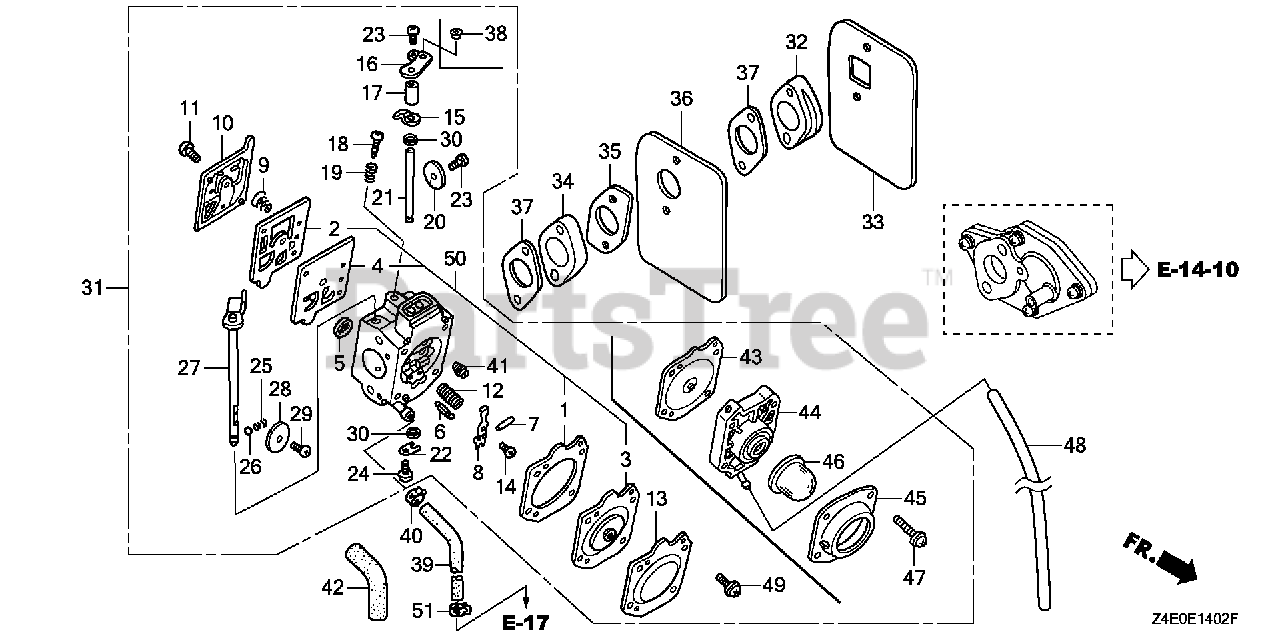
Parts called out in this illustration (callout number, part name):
1	GASKET, METERING DIAPHRAGM (CARBURETOR NO.)
2	GASKET, PUMP
3	DIAPHRAGM ASSY., METERING (CARBURETOR NO.)
4	DIAPHRAGM, PUMP
5	SCREEN, INLET (CARBURETOR NO.)
6	VALVE, INLET NEEDLE
7	PIN, METERING LEVER
8	LEVER, METERING
9	SPRING, PUMP
10	COVER, PUMP (CARBURETOR NO.)
12	SPRING (CARBURETOR NO.)
13	COVER, METERING DIAPHRAGM
14	SCREW (CARBURETOR NO.)
15	STOPPER, THROTTLE LEVER
16	LEVER, THROTTLE (CARBURETOR NO.)
17	SPACER, THROTTLE LEVER
18	SCREW, IDLE ADJUSTING (CARBURETOR NO.)
20	VALVE, THROTTLE (CARBURETOR NO.)
21	SHAFT, THROTTLE (CARBURETOR NO.)
22	CLIP, THROTTLE SHAFT
23	SCREW, VALVE
24	SCREW ASSY. (CARBURETOR NO.)
27	SHAFT ASSY., CHOKE (CARBURETOR NO.)
28	VALVE, CHOKE (CARBURETOR NO.)
31	CARBURETOR ASSY. (HDA 201E)
31	CARBURETOR ASSY. (HDA 201F)
32	INSULATOR, CARBURETOR
33	GASKET, INSULATOR
34	INSULATOR B, CARBURETOR
35	GASKET B, INSULATOR
36	PLATE, INSULATOR
37	GASKET, CARBURETOR
39	HOSE, FUEL (4.2X400) (FKM)
39	BULK HOSE, FUEL (4.5X3000) (4.5X120)
40	CLIP, TUBE (D8.5)
41	JET (#50) (CARBURETOR NO.)
41	JET (#52) (CARBURETOR NO.)
41	JET (#54) (CARBURETOR NO.)
49	SCREW ASSY. (CARBURETOR NO.)
51	CLIP, TUBE (D8.5)
